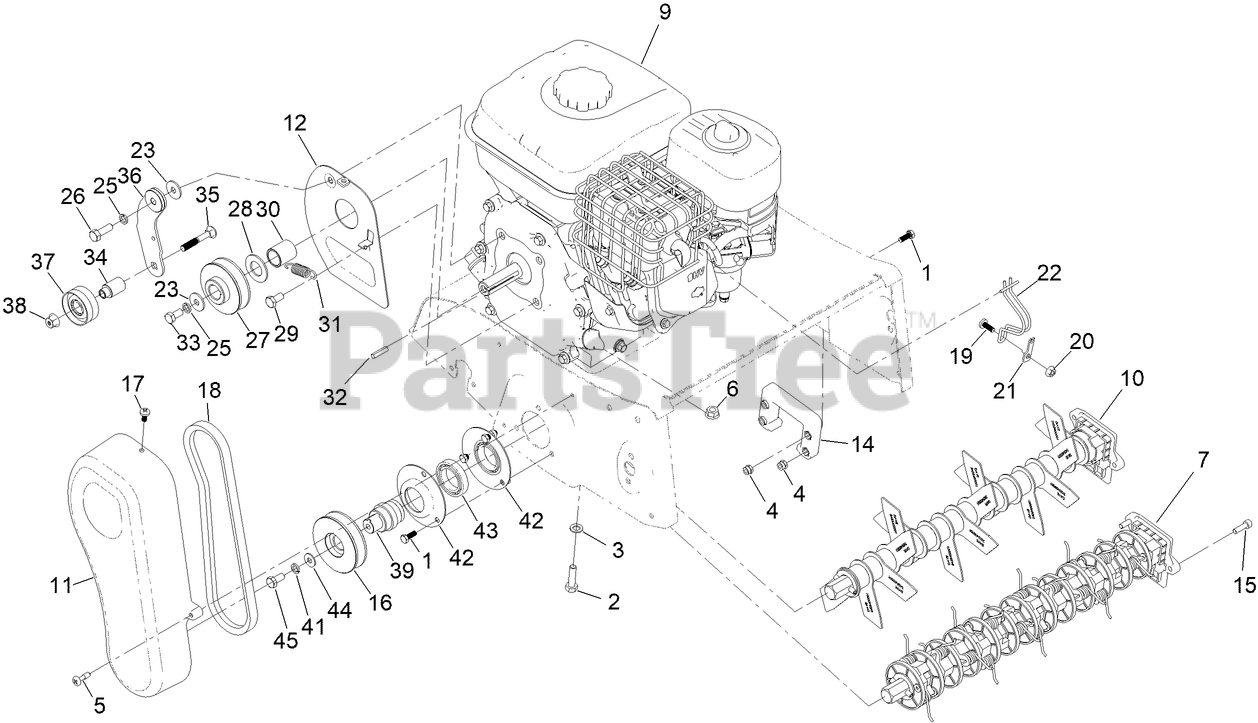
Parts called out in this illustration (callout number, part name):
1	BOLT-HEX
2	SCREW-HH
3	WASHER
4	NUT-LOCK, PREVAILING TORQUE
6	NUT-LOCK, FLANGE
7	SPRING TINE ASSEMBLY
9	ENGINE - BS XR750 HORIZONTAL
10	SCARIFIER BLADE SHAFT ASSEMBLY
11	GUARD-PULLEY
12	PLATE-PULLEY, ENGINE
14	DOCK-SHAFT, TINE
15	SCREW-SOCKET CAP HEAD
16	PULLEY-SHAFT, TINE
17	SCREW-PAN HEAD
19	CROSS SCREW M6X16
20	M6 HEX NUT
21	EXHAUST GUARD BRACKET
22	GUARD-EXHAUST
23	SPACER-SHAFT
25	WASHER- LOCK, SPRING
26	SCREW-HH
27	PULLEY
28	SPACER-SHAFT
29	BOLT-HEX
30	SHEATH
31	SPRING
33	BOLT-HEX
34	SLEEVE
35	BOLT-CARRIAGE
36	PULLEY ARM WELDED ASSY
37	BEARING
38	NUT-LOCK, PREVAILING TORQUE
39	COUPLER
41	WASHER- LOCK, SPRING
42	FLANGE
43	BEARING
44	WASHER
45	BOLT-HEX
